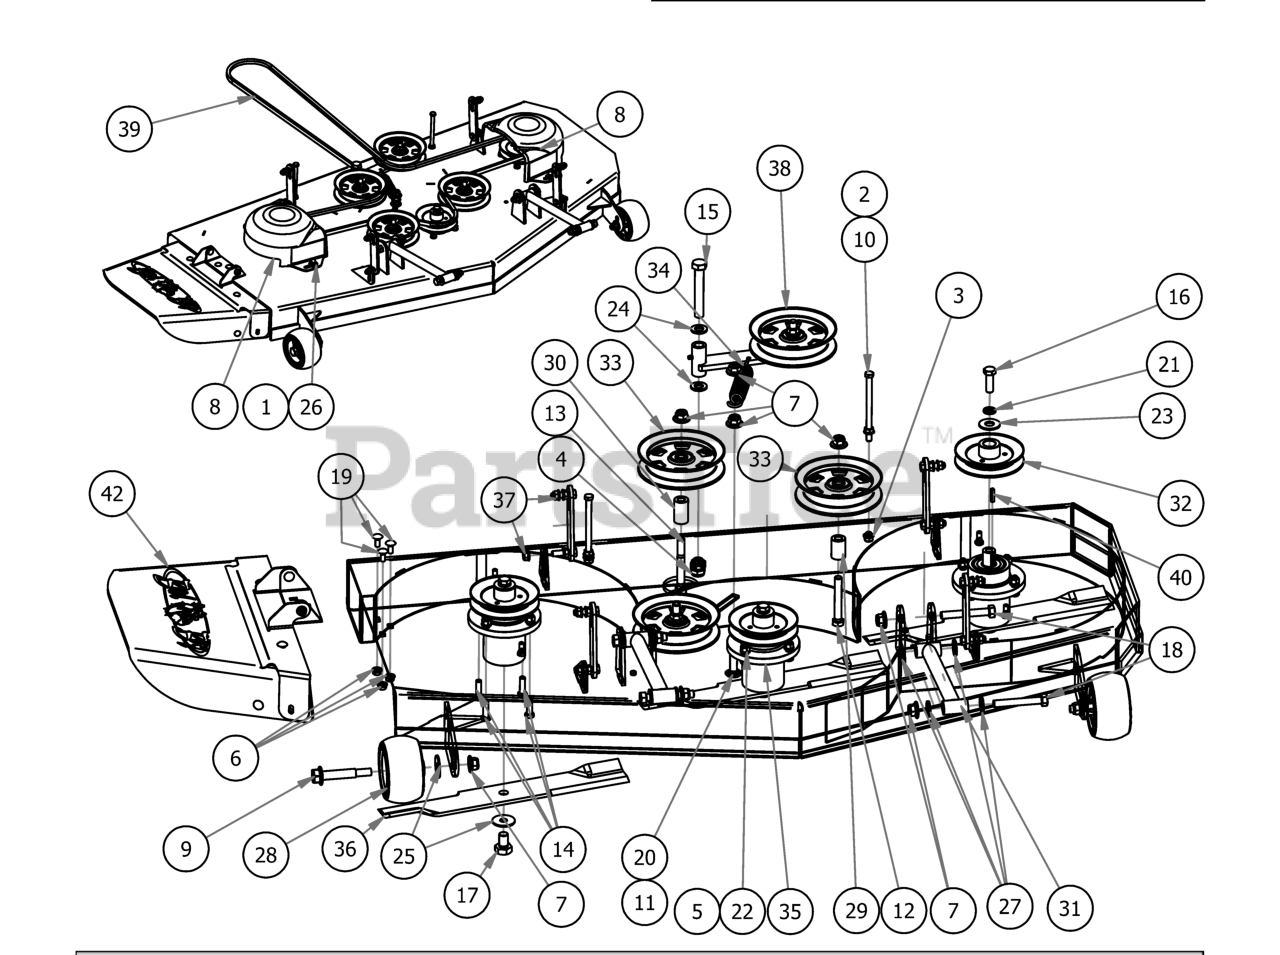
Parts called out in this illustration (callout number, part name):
1	Acorn nut-pulley Cover
2	3/8" Flange Nut
3	3/8" Nylock Flange Nut
4	5/8-11 Nylon Insert Jam Half Nut
5	3/8" Hex Nut
6	5/16-18 NYLON INSERT FLANGE LOCKNUT ZINC
7	1/2-13 NYLON INSERT FLANGE LOCKNUT ZINC
8	Pulley Cover
9	Deck Wheel Bolt
10	3/8-16 X 5-1/4 HEX CAP SCREW (GR.5) ZINC
11	1/2 x 2" Carriage Bolt
12	1/2 x 3 1/2 Flange Bolt Grade 8
13	1/2" x 4" Bolt (Grade 8)
14	3/8" x 1 1/4" Hex Bolt
15	5/8" x 4" Hex Bolt
16	1/2"-20 x 1 1/2 - Grade 5 Fine Thread Bolt
17	5/8" x 1 1/2" Grade 8 Hex Bolt (Fine)
18	1/2-13 x 3 1/2 GR 5 Hex Bolt
19	5/16-18 x 3/4 Carriage Bolt
20	.517 Square Hole Round Washer
21	1/2" Lock Washer
22	3/8" Lock Washer
23	5/8'' Flat Washer
24	.630 ID Plastic Washer
25	1/2" Belleville Washer
26	.360 ID Plastic Washer-Black
27	.505 Nylon Spacer
28	Deck Wheel
29	.502 ID X .750 OD X 1.500 Long Spacer
30	1 3/4" Pulley Spacer
31	MZ/ZT Deck Locator
32	54 MZ Spindle Pulley
33	5-3/4 Idler Pulley
34	Deck Idler Spring
35	Spindle Assembly-MZ
36	54" Deck Fusion Blade For Outlaw
37	Deck Hanger Assembly
38	2017 54"/48" Deck Idler Assembly
39	B155.75 Deck Belt
40	3/16 X 1 SQ MACHINERY KEY 1018 STL ZINC
41	2017 54" MZ Magnum Deck
42	MZ Discharge Chute Assembly
